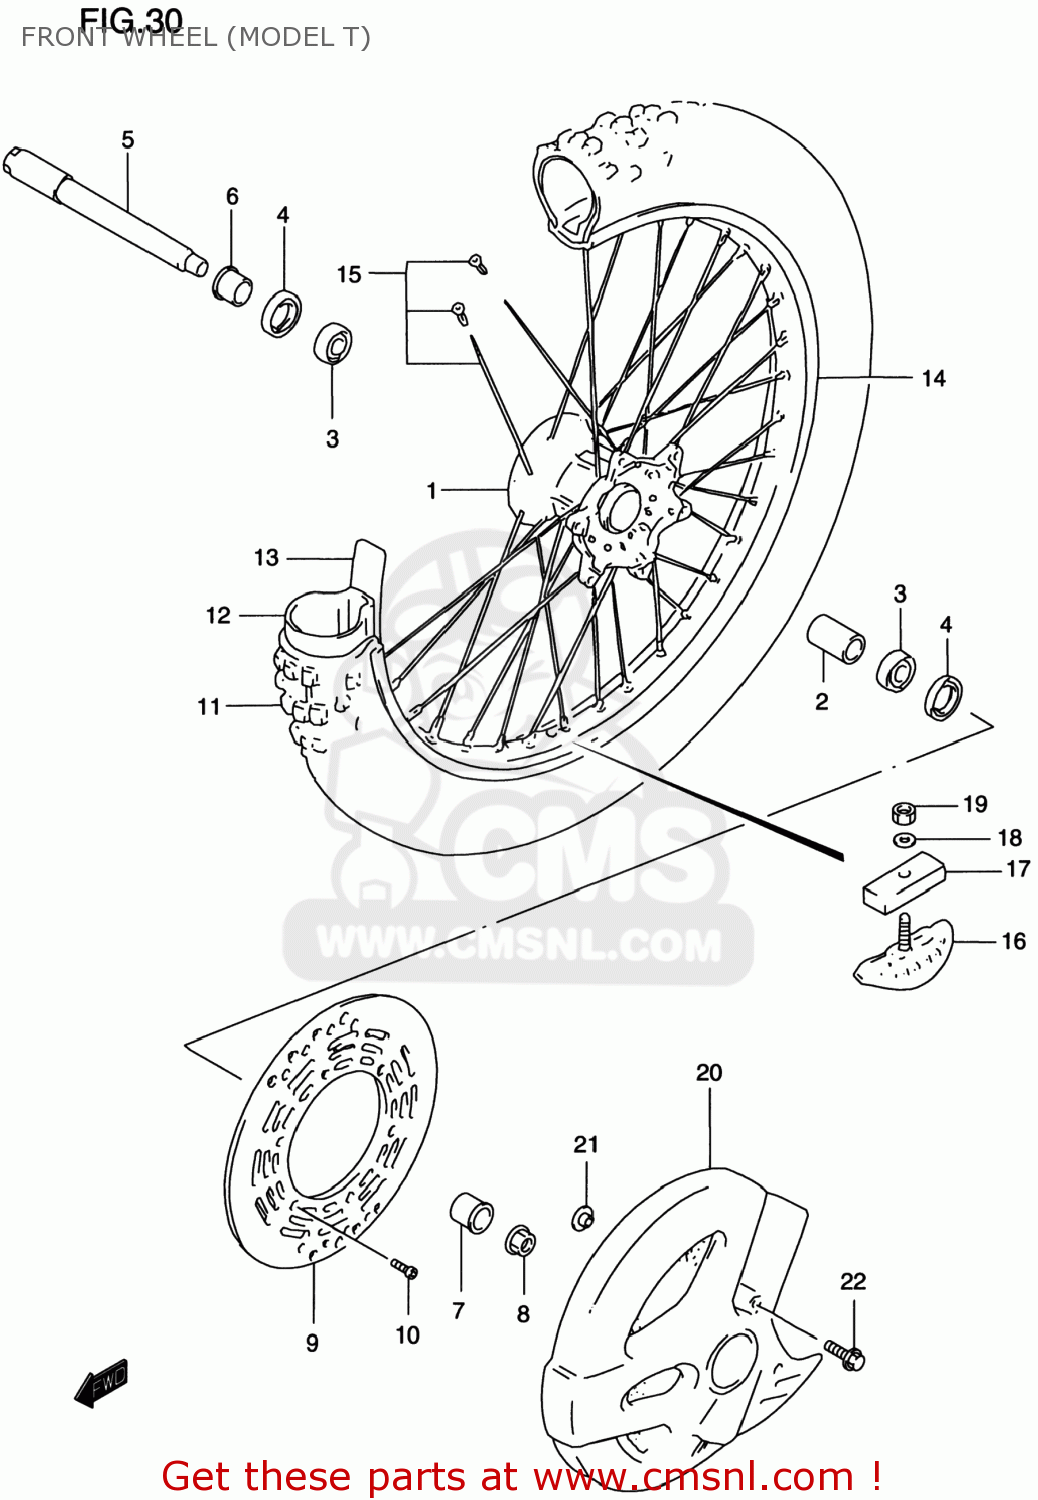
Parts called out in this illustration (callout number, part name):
1	HUB,FR WHEEL
2	SPACER,FR HUB BEARING
3	BEARING
4	SEAL,OIL(25X37X6)
5	AXLE,FRONT
6	SPACER,FRONT AXLE,RIGHT
7	SPACER,FR AXLE,L
8	NUT
9	DISC,FR BRAKE
10	SCREW
11	TIRE, FRONT
12	TUBE
13	PROTECTOR,WHEEL INNER
14	RIM,FRONT WHEEL (1.60X2
15	SPOKE SET,FR WHEEL
16	STOPPER,BEAD
17	CUSHION,BEAD STOPPER
18	WASHER
19	NUT
20	COVER,FRONT BRAKE DISC
21	WASHER
22	BOLT(6X16)
